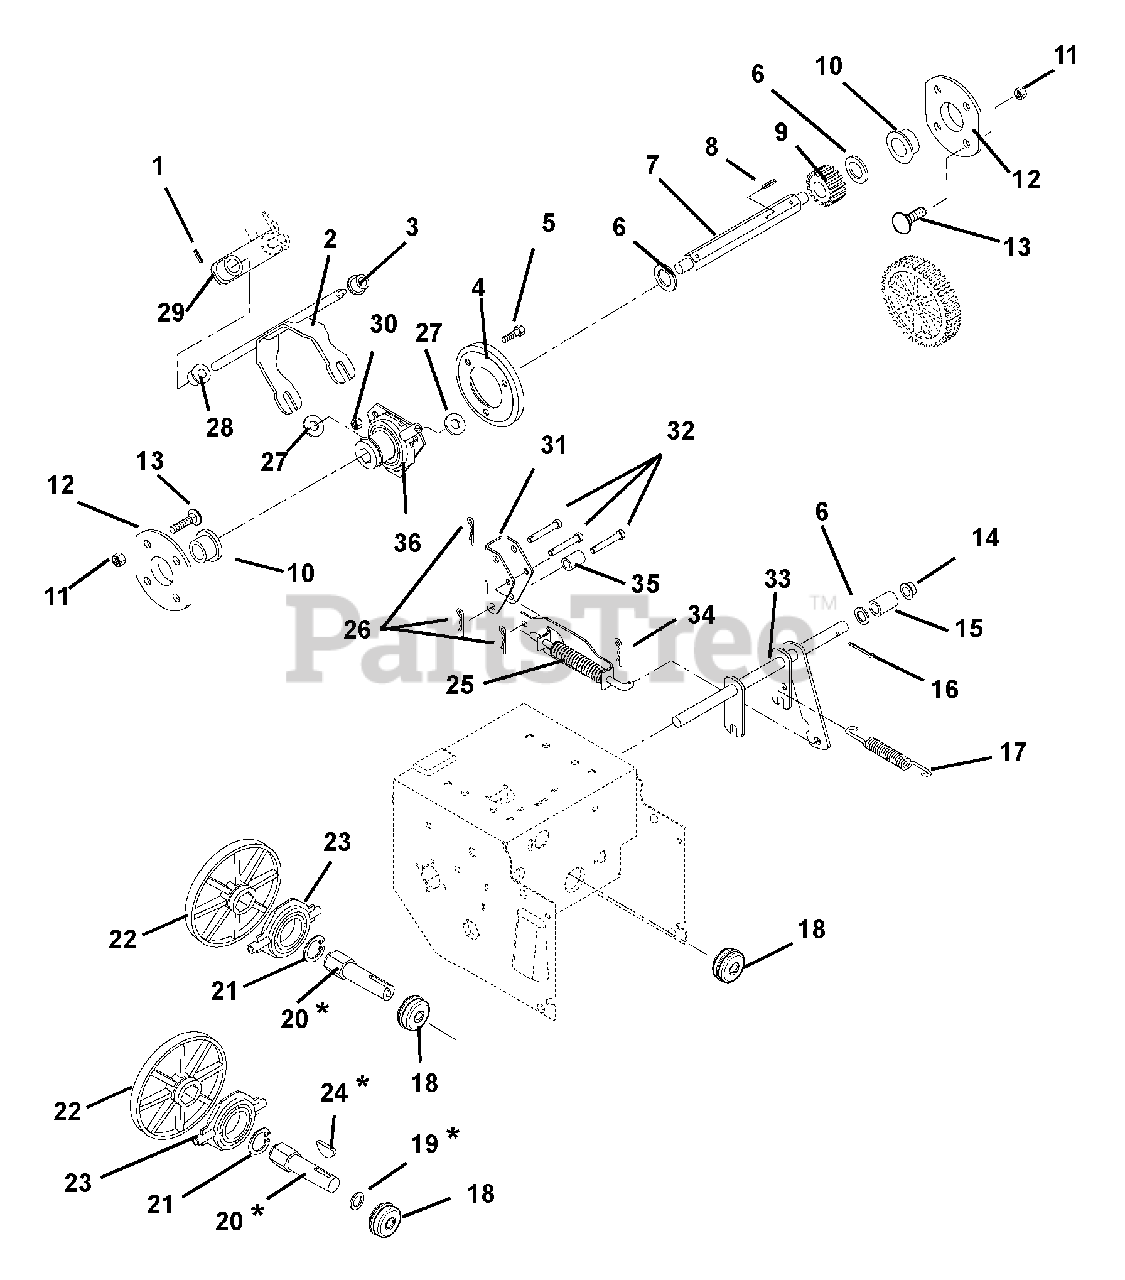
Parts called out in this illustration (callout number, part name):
1	PIN-ROLL .156X.88
2	FORK-SPEED
3	BSHG-FLG .325X.444X.440X.560
4	DISC, FRICTION - 730 MAT'L
5	@BLT-HEX .25-20X.50 GR5 YWZC
6	@WSHR-FL-STL.531X1.06X.095YWZC
7	HEX SHAFT
8	PIN-ROLL .125X.88
10	BSHG-FLG .500X.750X.625X.937
11	NUT-LK-DUAL FACE 10-24 YWZC
12	FLANGE AND BUSHING
13	BLT-RDHDSQSHK #10-24X.38 GR2YW
14	CAP, .50 ROD YWZC
15	SPACER .504X.748X.321
16	@PIN-CTR .12X1.00 EXTPRSQCT YZ
17	SG-TENS .063X.44X1.56
18	BRG-BALL,.625X1.38X.43 SNAP RG
19	WSHR, THRUST .625X1.125X.063
20	SPINDLE SHAFT, 932 DRIVE PLATE
21	RG-RTNG-EXT 1.250X.050
22	FRICTION PLATE
23	BEARING ASSEMBLY
24	KEY-WDRF .188X.75X.313 SAE 9
25	TRACTION CLUTCH ASSY
26	PIN-HAIR INT .06X.18X.77
27	WSHR-FL-STL .505X1.00X.062YWZC
28	BSHG-FLG .500X.625X.500X.750
29	ARM, SPEED CONTROL
30	@NUT-LK-CTR .25-20 YWZC
31	BRACKET, TRACTION ARM
32	PIN,CLEVIS .243/.248 X 1.38 YZ
33	CLUTCH FORK
34	PIN-HAIR INT .08X.18X1.18 YWZC
35	SPACER .325 X.625 X.455
36	SHIFT CARRIER
